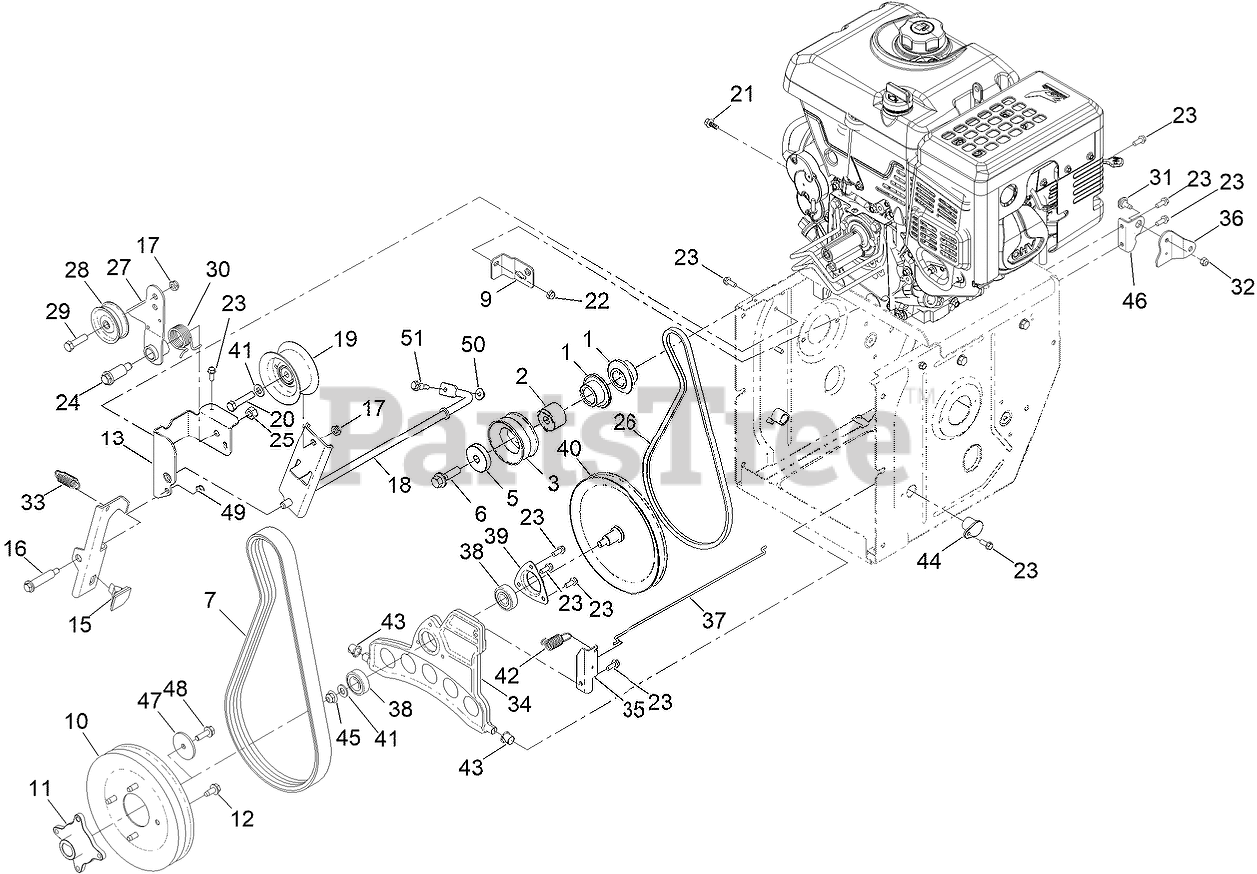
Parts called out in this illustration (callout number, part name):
1	PULLEY-TRACTION, ENGINE
2	PULLEY-SPACER
3	PULLEY-IMPELLER, DOUBLE SHEAVE
5	SUPPORT-PULLEY
6	BOLT-BLADE
7	BELT-V
9	BRACKET-CLUTCH, IMPELLER
10	PULLEY-IMPELLER, DOUBLE SHEAVE
11	HUB-PULLEY
12	SCREW-HWHTF
13	BRACKET-BRAKE, CLUTCH
15	PAD-BRAKE
16	BOLT-SHOULDER
17	NUT-HEX
18	ARM-CLUTCH, IMPELLER
19	PULLEY, IDLER
20	SCREW-HH
21	SCREW-HHF
22	NUT-HF
23	SCREW-HWH
24	BOLT-SHOULDER
25	NUT-HEX
26	V-BELT
27	ARM-IDLER, TRACTION
28	PULLEY-IDLER
29	SCREW-HH
30	SPRING-TORSION
31	SCREW-SHOULDER
32	NUT-HEX
33	SPRING-EXTENSION
34	PLATE-FRICTION, WHEEL
35	BRACKET-PLATE, TRACTION
36	BELLCRANK-DRIVE
37	LINK-DRIVE
38	BEARING-BALL
39	RETAINER-BEARING
40	PULLEY-TRACTION
41	WASHER-FLAT
42	SPRING-EXTENSION
43	BUSHING-NYLINER
44	BUSHING-PLATE, TRACTION
45	NUT-HF, NI
47	WASHER-PLAIN
48	SCREW-HHF
49	NUT-HEX
50	NUT-HF
51	BOLT-SHOULDER
